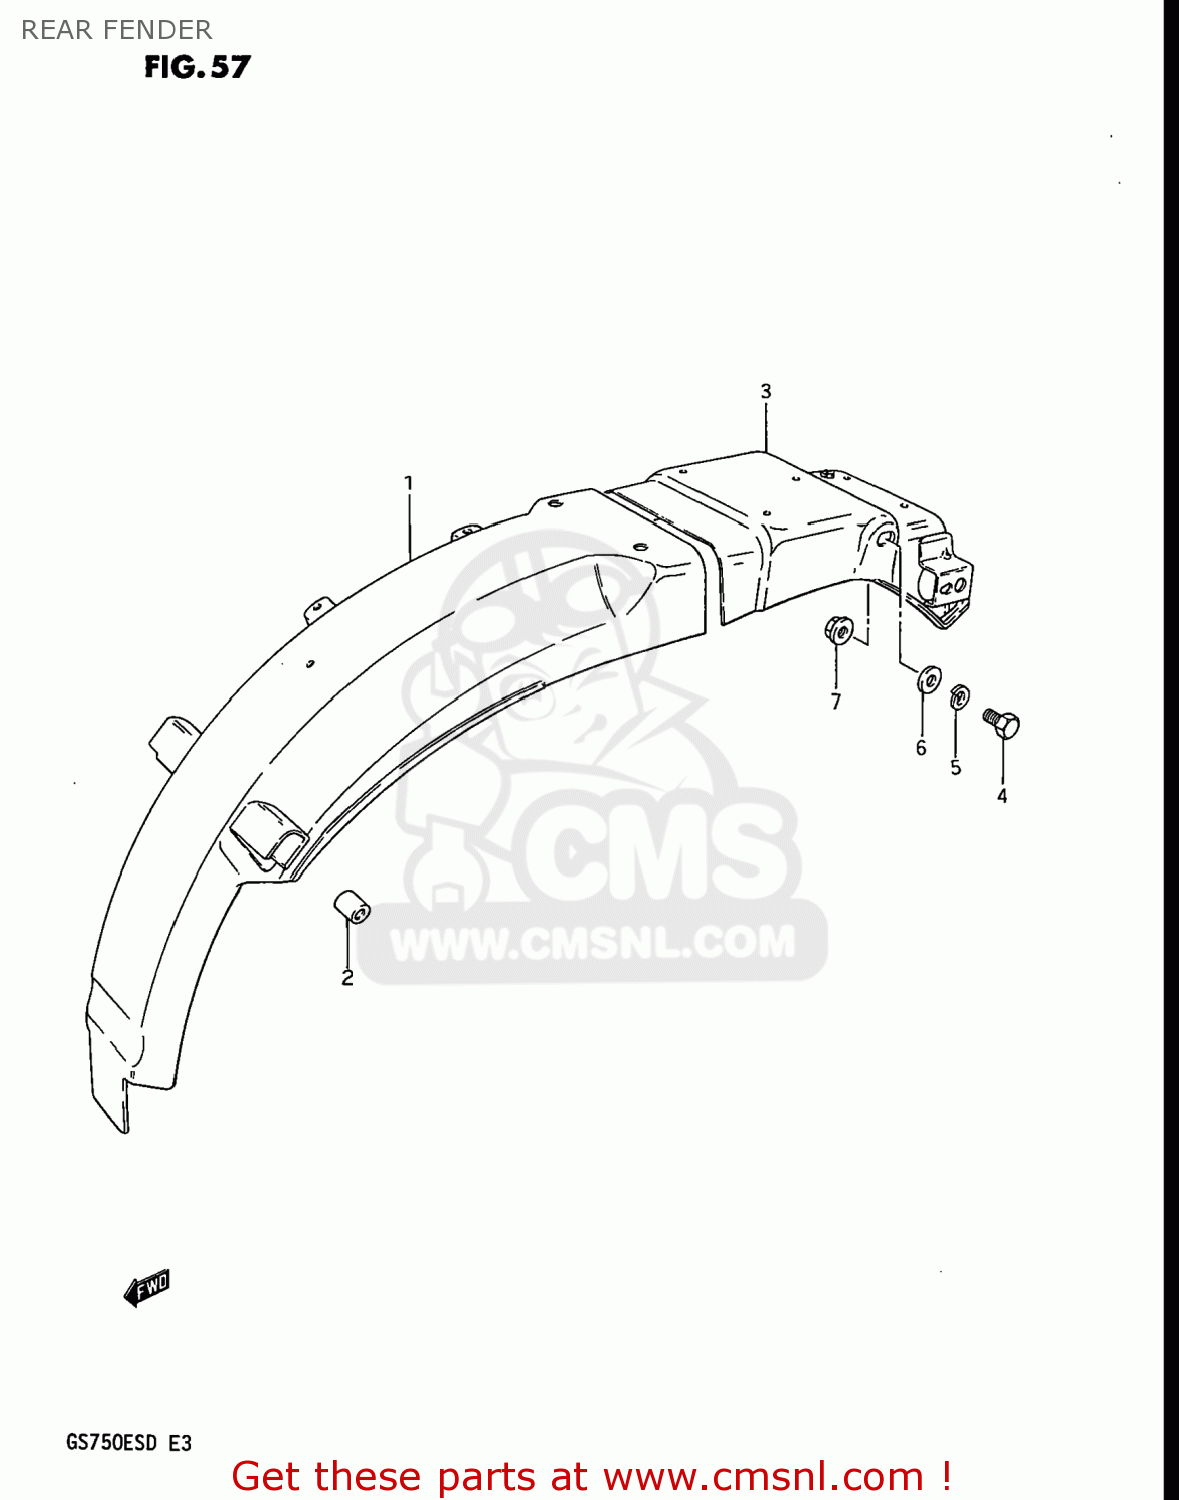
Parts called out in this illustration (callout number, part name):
1	BODY,REAR FENDER,FRONT
2	CUSHION
3	REINFORCEMENT,RR FENDER
4	BOLT
5	LOCK WASHER
6	WASHER
7	NUT
